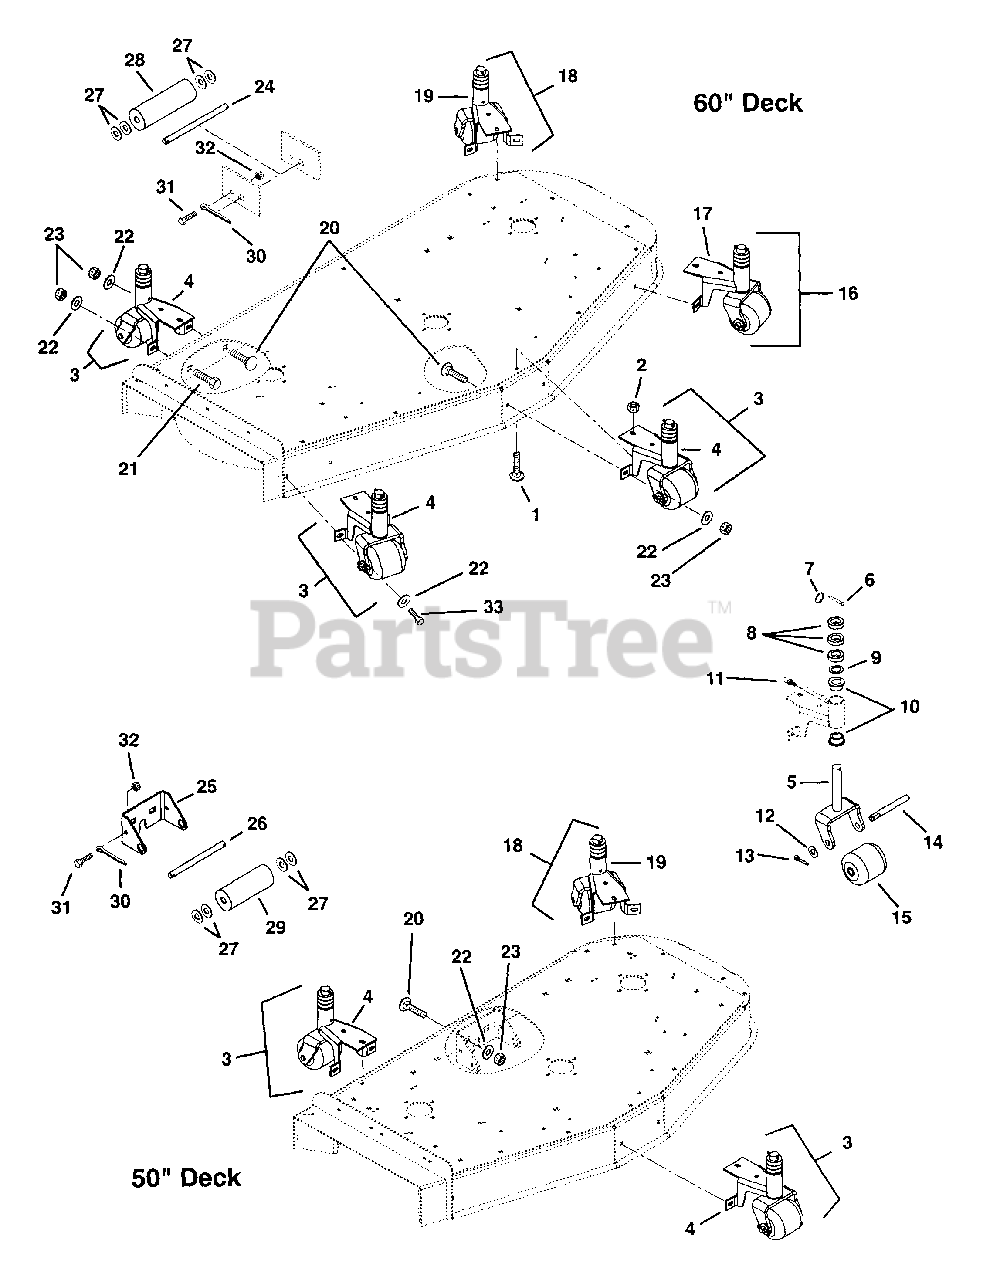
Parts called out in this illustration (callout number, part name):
1	Bolt-Round Head Square Neck .38-16 x 1.25 Grade 2 (60" Deck)
1	Bolt-Round Head Square Neck .38-16 x 1.25 Grade 2 (50" Deck)
2	Nut-Locking-Nylon .38-16 (60" Deck)
2	Nut-Locking-Nylon .38-16 (50" Deck)
3	Assembly, Roller Bracket (60" Deck)
3	Assembly, Roller Bracket (50" Deck)
4	Weldment-Roller Bracket
5	Weldment-Roller Fork
6	Pin-Clevis .19 x 2.00
7	Kickout Ring
8	Bushing-Sleeve 1.04 x 1.75 x .500
9	Washer-Hardened Thrust 1.00 x 1.55 x .03
10	Bushing-Flange 1.020 x 1.385 x .75 x 1.75
11	Fitting-Lube .25-28 Taper
12	Washer-Flat Steel .656 x 1.31 x .095
13	Pin-Cotter .25 x 1.00
14	Shaft, Castor
16	Assembly, Roller Bracket-Left Front (60" Deck)
17	Weldment-Roller Bracket-Left Front (60" Deck)
18	Assembly, Roller Bracket-Left Rear
19	Weldment-Roller Bracket-Left Rear
20	Bolt-Round Head Square Neck .38-16 x 1.00 Grade 2
21	Bolt-Hex .38-16 x 1.00 Grade 5 (60" Deck)
22	Washer-Flat-Steel .38 x .875 x .083 (60" Deck)
22	Washer-Flat-Steel .38 x .875 x .083 (50" Deck)
23	Nut-Locking-Nylon .38-16 (60" Deck)
23	Nut-Locking-Nylon .38-16 (50" Deck)
24	Shaft, Center Roller (60" Deck)
25	Bracket, Roller (50" Deck)
26	Rod (50" Deck)
27	Washer-Flat-Steel .656 x 1.31 x .095
28	Roller, Gage (60" Deck)
29	Roller, Gage (50" Deck)
30	Pin-Cotter .25 x 2.00
31	Bolt-Hex .25-20 x .75 Grade 5
32	Nut-Locking-Center .25-20
33	Bolt-Hex .31-18 x 1.00 Grade 2 (60" Deck)
